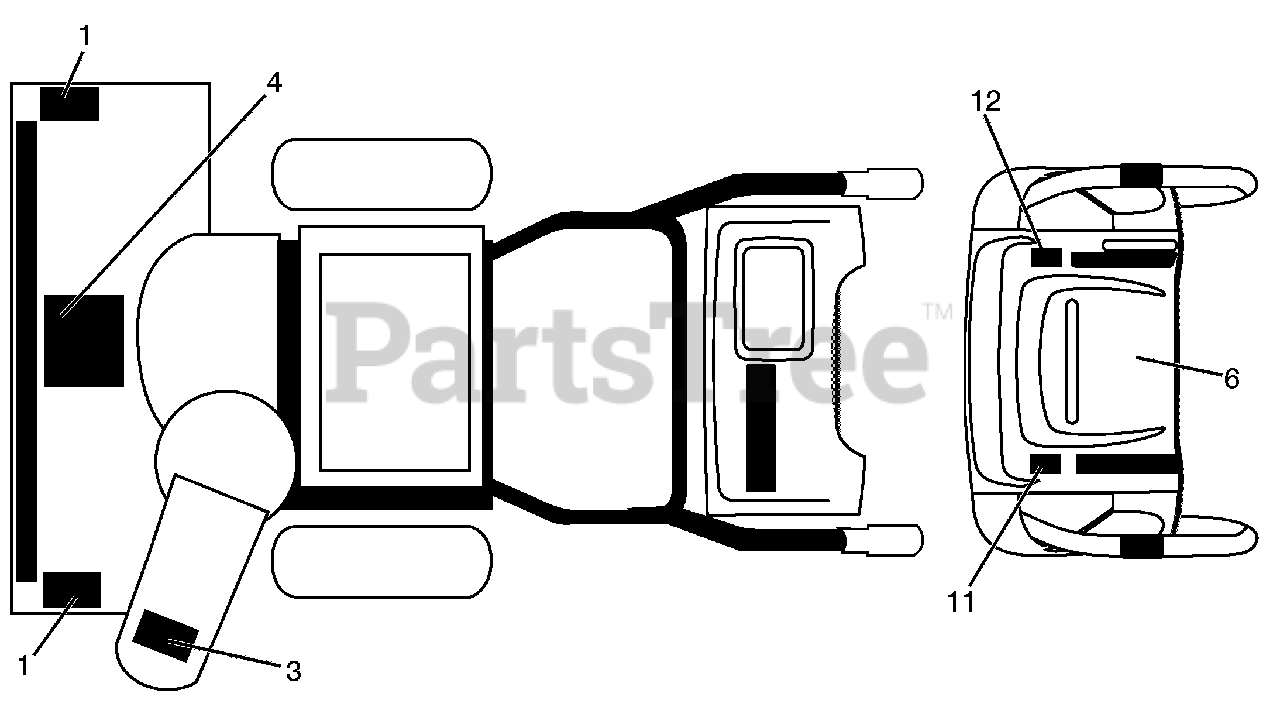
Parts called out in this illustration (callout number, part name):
1	DECAL, DANGER
3	DECAL, DANGER, DEFLECTOR
4	DECAL, DANGER
6	DECAL, INSTRUCTION
11	DECAL, LH CONS. SPD/LEV/PWST
12	DECAL, RH CONS. SPD/LEV/PWST
12	OWNER'S MANUAL, ENGLISH
12	OWNER'S MANUAL, FRENCH
